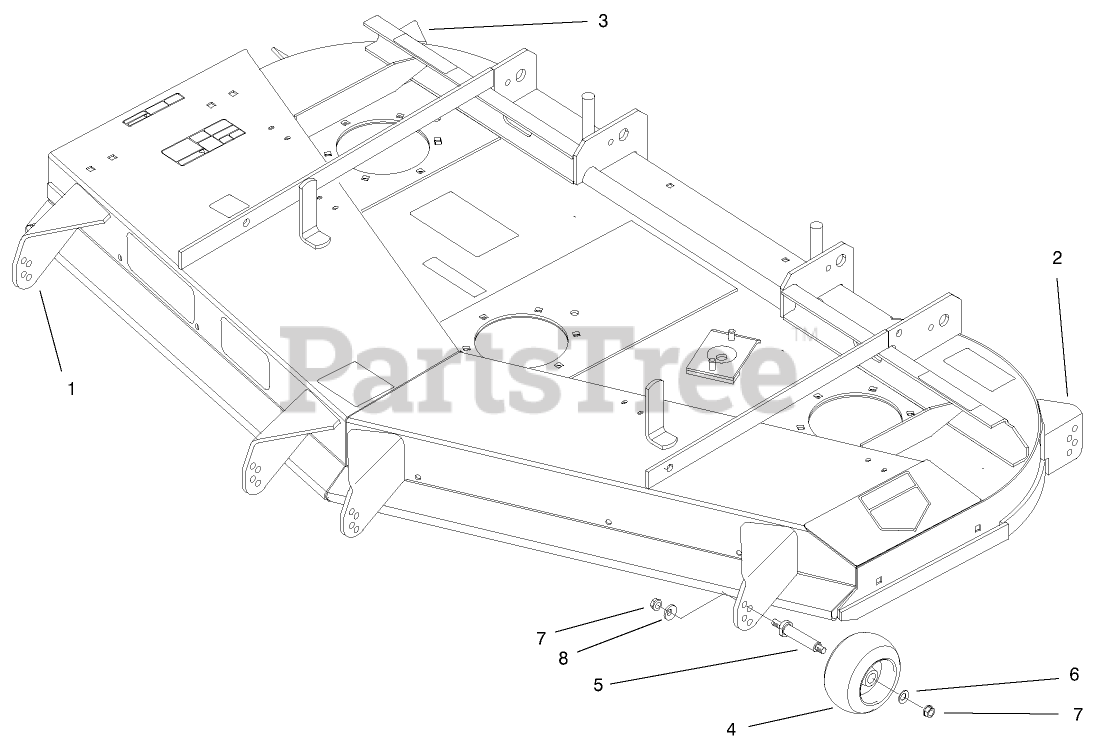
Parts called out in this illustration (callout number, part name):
1	Bracket-Right
2	Gusset-Rear, LH
3	Gusset-Rear, RH
4	WHEEL-GAGE
5	SPACER
6	Washer
7	NUT-HHF, WHIZ
8	WASHER-BELLEVILLE
